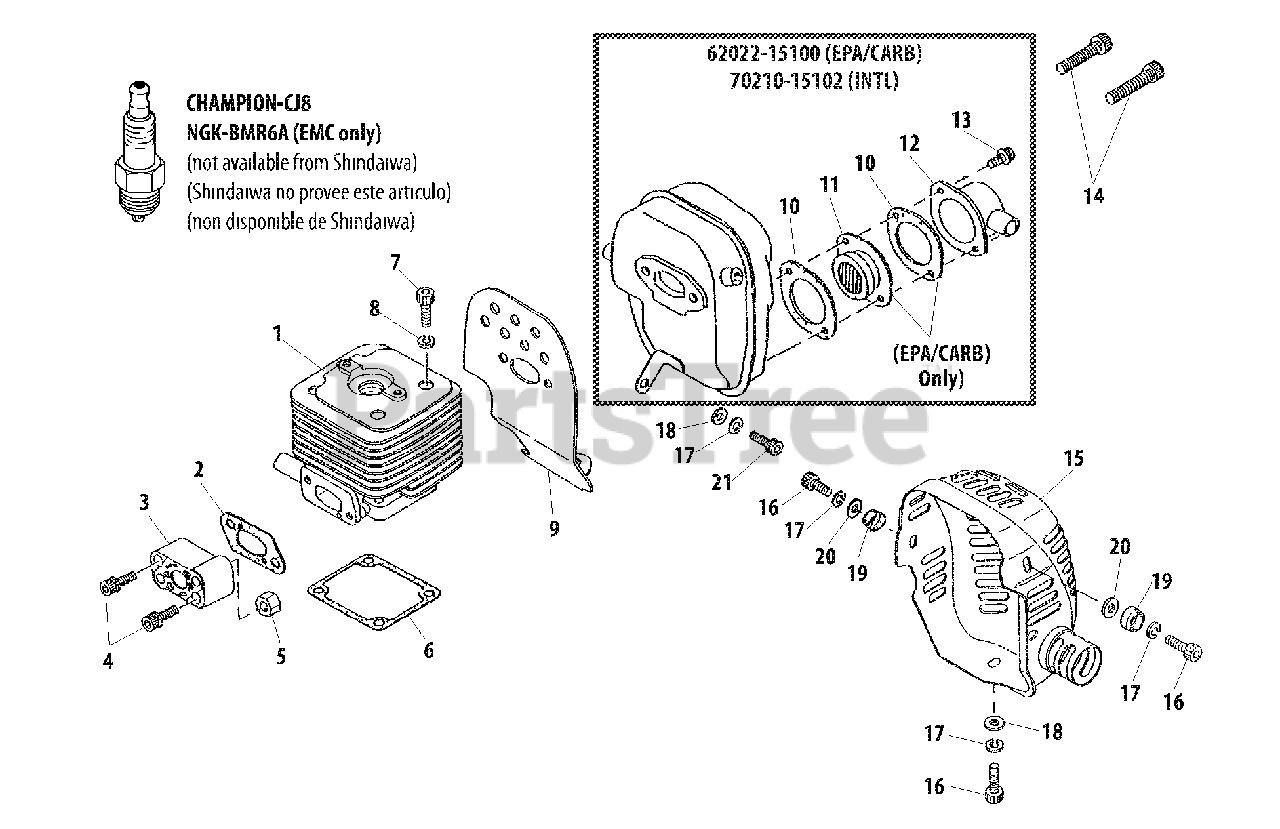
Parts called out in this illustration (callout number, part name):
1	CYLINDER
2	GASKET, INTAKE
3	INSULATOR
4	SCREW - 5X25
5	NUT
6	GASKET, CYLINDER
7	SCREW - 5X25
8	LOCKWASHER - 5
9	GASKET, EXHAUST
10	GASKET, EXHAUST
11	SCREEN, SPARK ARRESTOR
12	GUIDE, EXHAUST
13	SCREW - 4X8
14	SCREW - 6X25
15	COVER, MUFFLER
16	SCREW - 5X10
17	LOCKWASHER - 5
18	WASHER - 5
19	COVER
20	WASHER
21	BOLT
62022-15100	MUFFLER ASSY
70210-15102	MUFFLER ASSY
